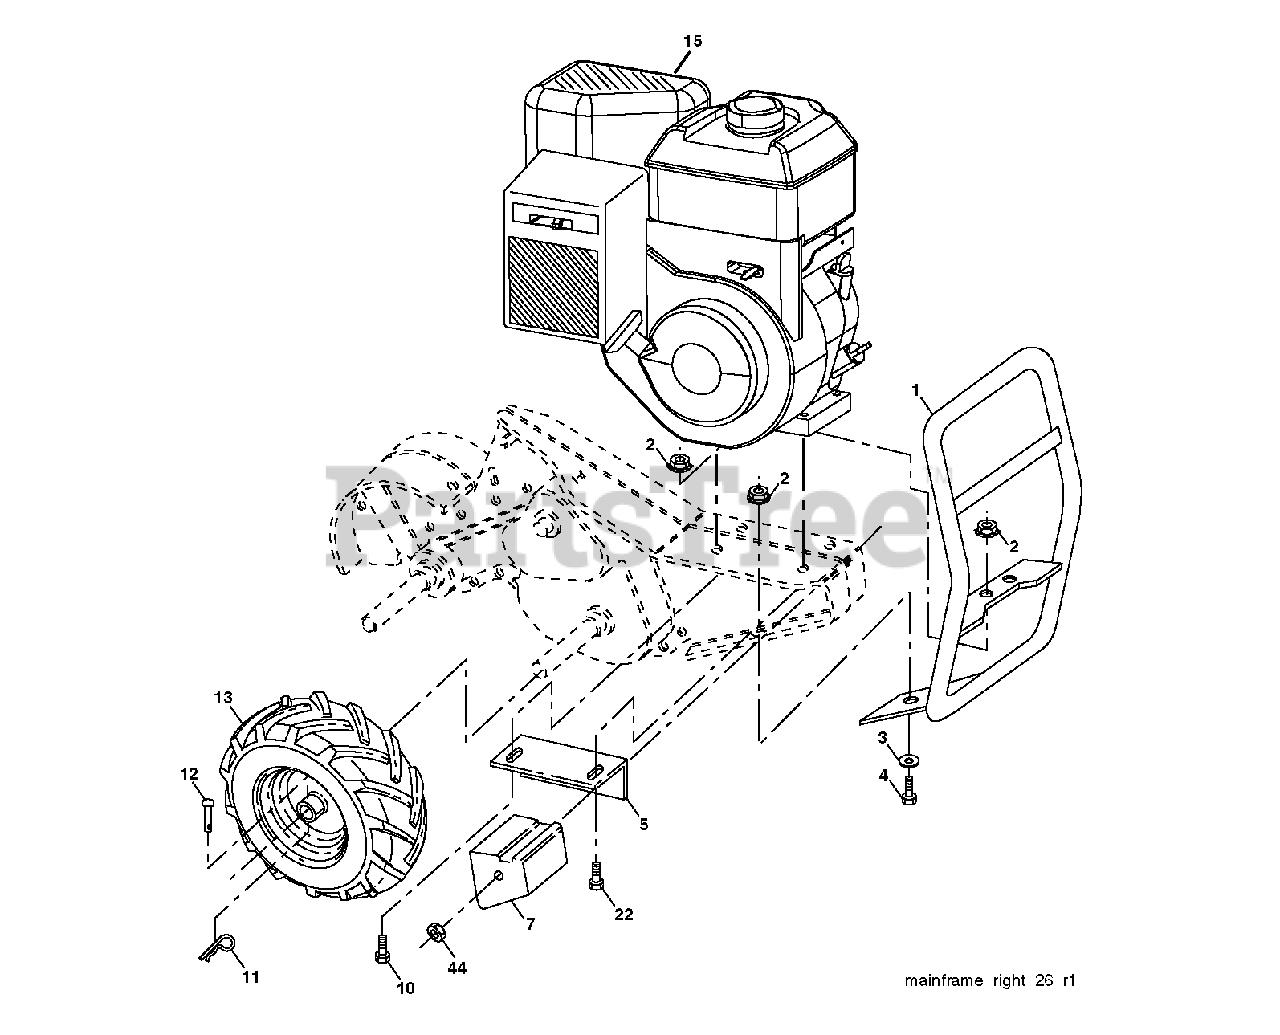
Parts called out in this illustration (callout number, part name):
1	BUMPER.ASM.TILLER.
2	LOCKNUT-FLANGE 5/16-18
3	WASHER
4	BOLT
5	BRACKET RH CRT
6	BOLT, HEX 5/16-18X1-3/4
7	COUNTERWEIGHT, RH
10	BOLT
11	RETAINER M
12	RIVET,DRILLED
13	RIM
13	VALVE STEM LT
